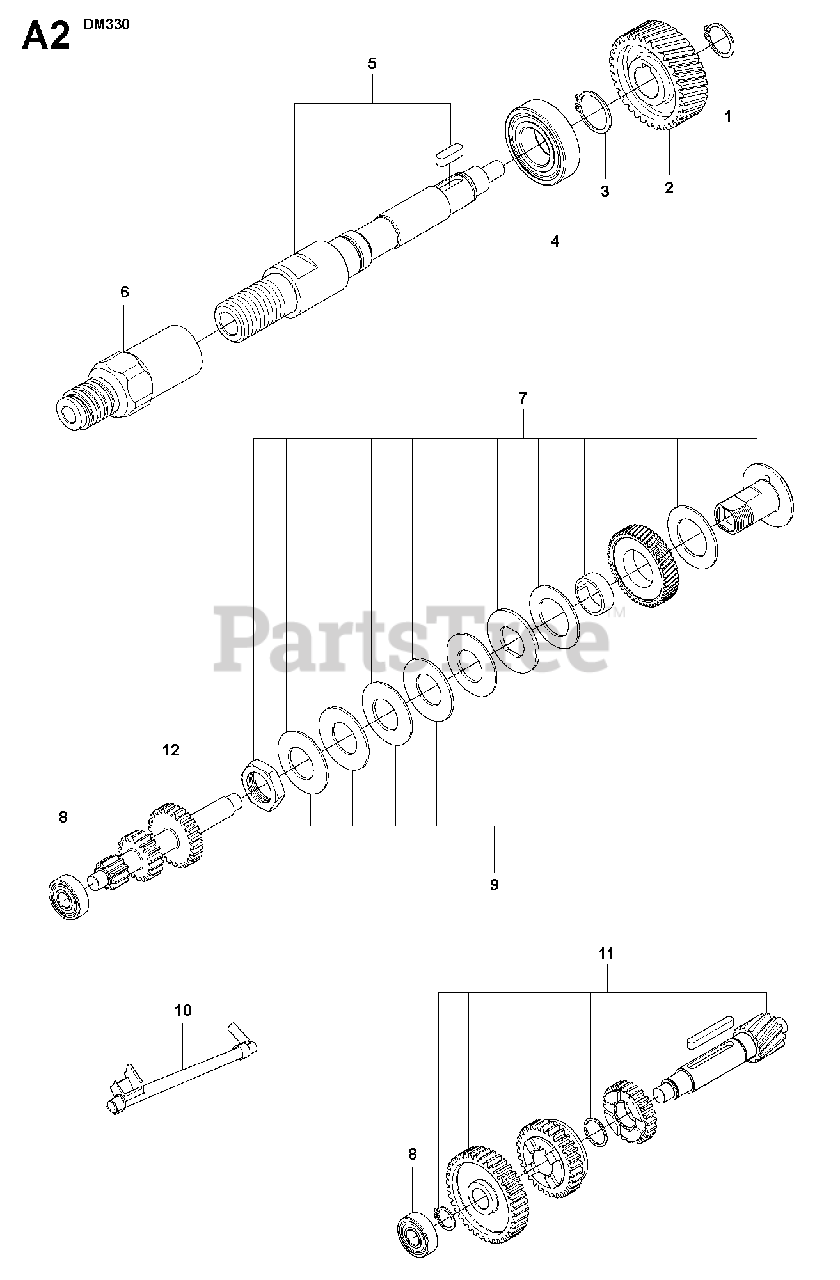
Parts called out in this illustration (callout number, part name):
2	GEAR WHEELLow speed version
2	GEAR WHEELHigh speed version
6	ADAPTERSE, FI, NO, DK
8	BALL BEARING
11A	GEAR WHEEL ASSYLow speed version
11B	GEAR WHEEL ASSYHigh speed version
